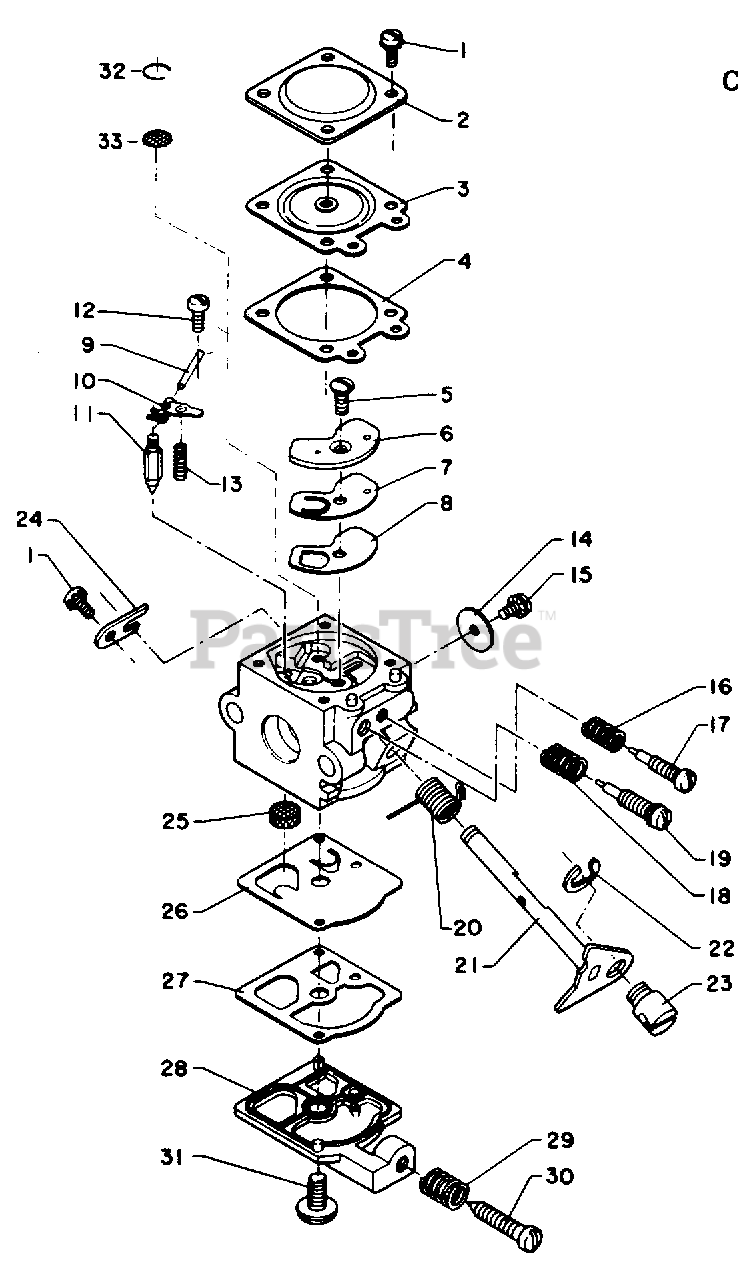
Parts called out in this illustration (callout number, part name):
1	Screw & lock washer
2	Metering diaphragm cover
3	Metering diaphragm
4	Metering diaphragm gasket
5	Circuit plate screw
6	Circuit plate
7	Circuit diaphragm
8	Circuit plate gasket
9	Metering lever pin
10	Metering lever
11	Inlet needle valve
12	Metering lever pin screw
13	Metering lever spring
14	Throttle valve
15	Shutter screw
16	I. needle adjust spring
17	Idle needle
18	H.S. needle adjust spring
19	H.S. needle
20	Throttle return spring
21	Throttle shaft
22	Swivel clip
24	Throttle shaft clip
25	Inlet screen
26	Pump diaphragm
27	Pump gasket
28	Pump cover
29	Idle adjust spring
30	Idle adjust screw
31	Pump cover screw
32	Ring - Screen Retainer
33	Screen - Check Valve
